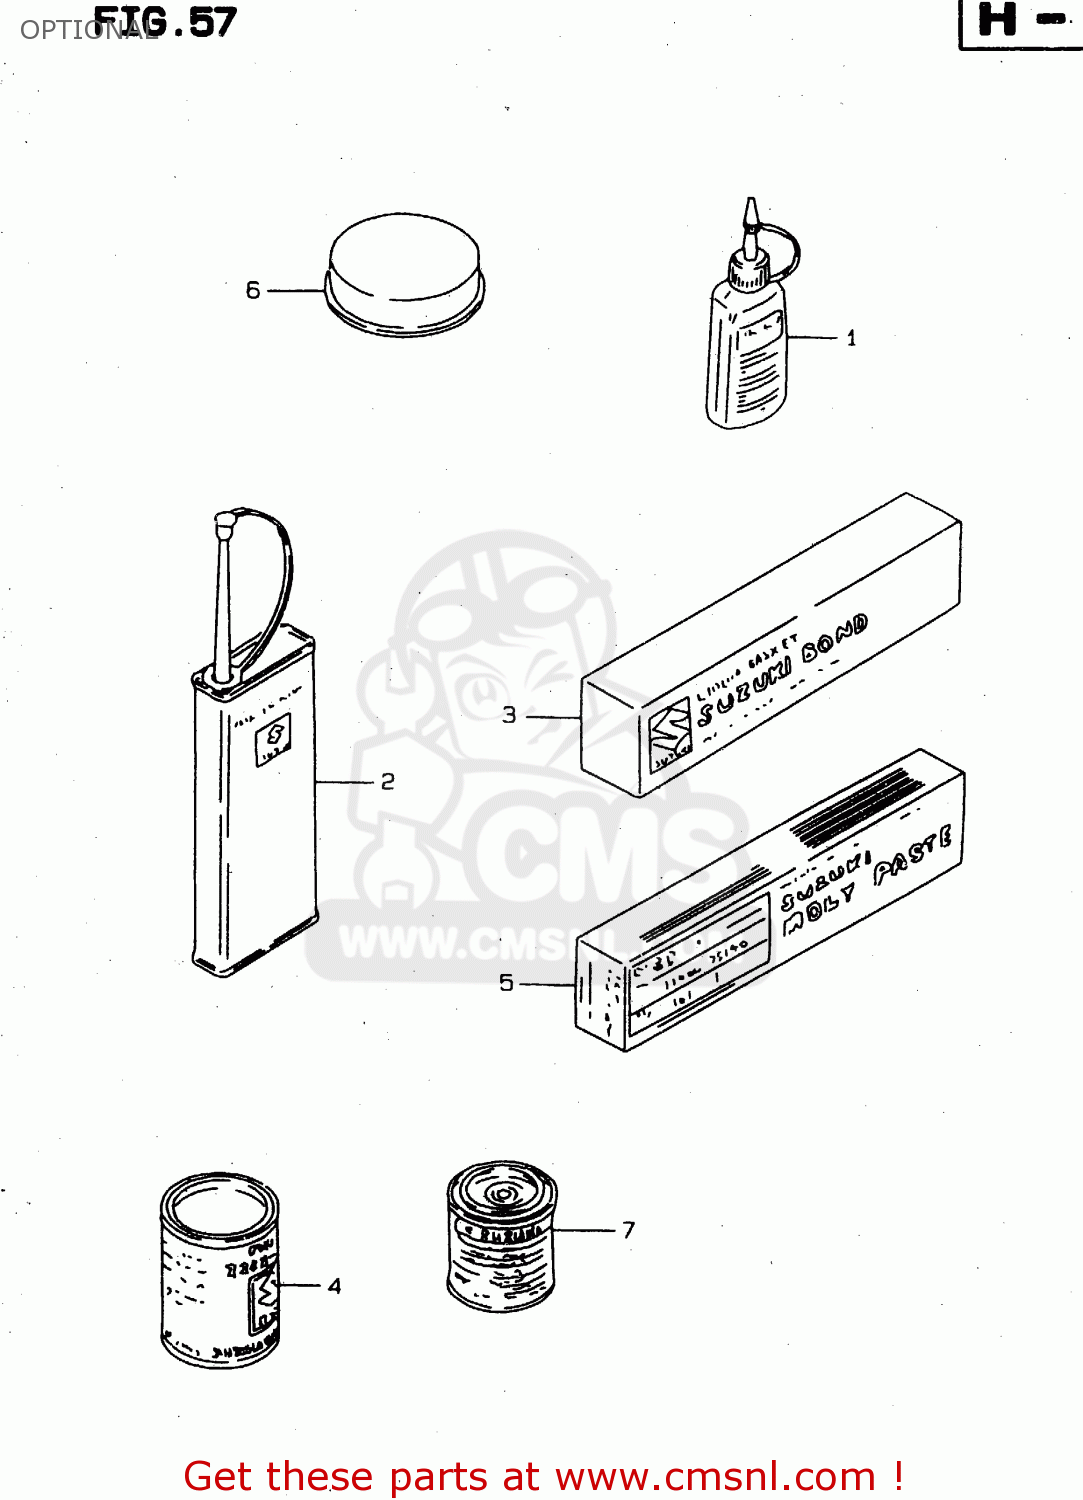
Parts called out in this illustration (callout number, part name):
1	THREAD LOCK NO.1342
2	THREAD LOCK NO.1401 CLEAR 200G
3	LIQUID GSKT NO.1215 250G
4	GREASE(C)EP2 LITHIUM 150G
5	SUZUKI MOLY PASTE
6	GREASE,PBC FOR BRK PAD 20G
7	PAINT BLIGHT S
